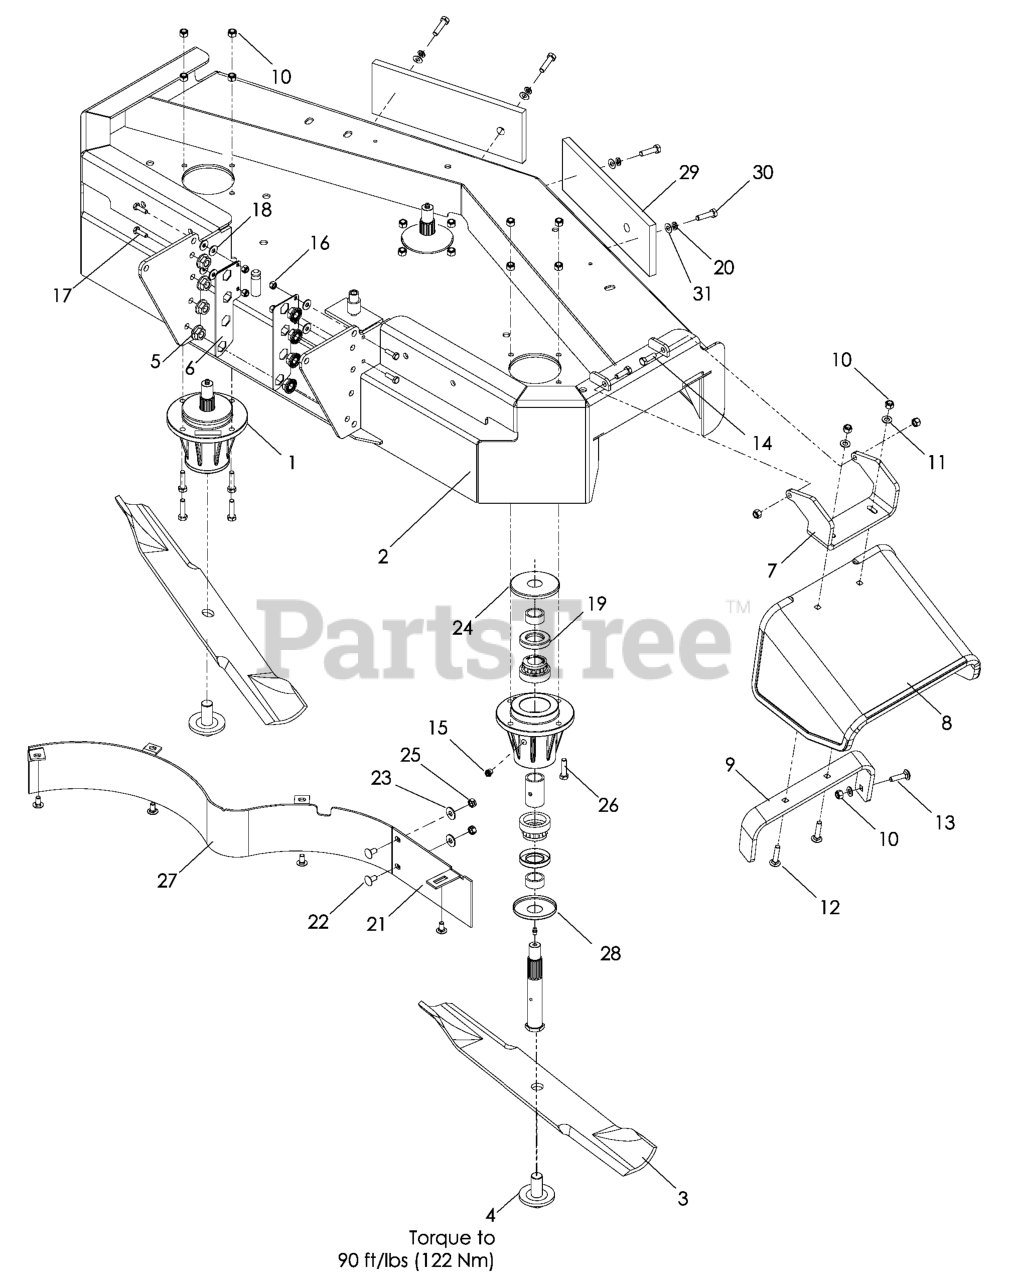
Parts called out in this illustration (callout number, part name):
1	HOUSING ASM, 72
2	DECK SVC W/DECALS WH4818
3	BLADE OEM 16 1/4"
4	BLADE BOLT/WASHER
5	NUT FLANGE 1/2-13 GR 5
6	PLATE NUT - PAINTED
7	HINGE CHUTE - BLACK
8	CHUTE, RUBBER DISCHARGE WB
9	BRKT, REINF-CHUTE WB
10	NUT 5/16 NYLOC
11	FLAT WASHER 5/16 SAE
12	RHSNB 5/16-18 X 1-1/2 GR 5 ZD
13	BOLT, CARRIAGE 5/16X1-1/4
14	HCS 5/16C X 1
15	ZERK
16	NUT.1/4-20.HEX.NYLOC.ZD
17	HCS 1/4-20X7/8 GR5
18	WASHER 1/4 FLAT
19	SHAFT SEAL
20	WASHER 1/2" SPLIT LOCK
21	CENTER BAFFLE 48"
22	CARRIAGE BOLT 5/16C X 5/8"
23	WASHER 5/16 FLAT
24	TOP DUST CAP
25	NUT 5/16C CENTERLOCK
26	HCS 5/16C X 1 1/4
27	BAFFLE WLDT, BLACK
28	BOTTOM DUST CAP
29	WEIGHT, COUNTER, ORANGE
30	HCS 1/2-13 X 1-1/2 GR 5 ZD
31	WASHER 1/2" FLAT
